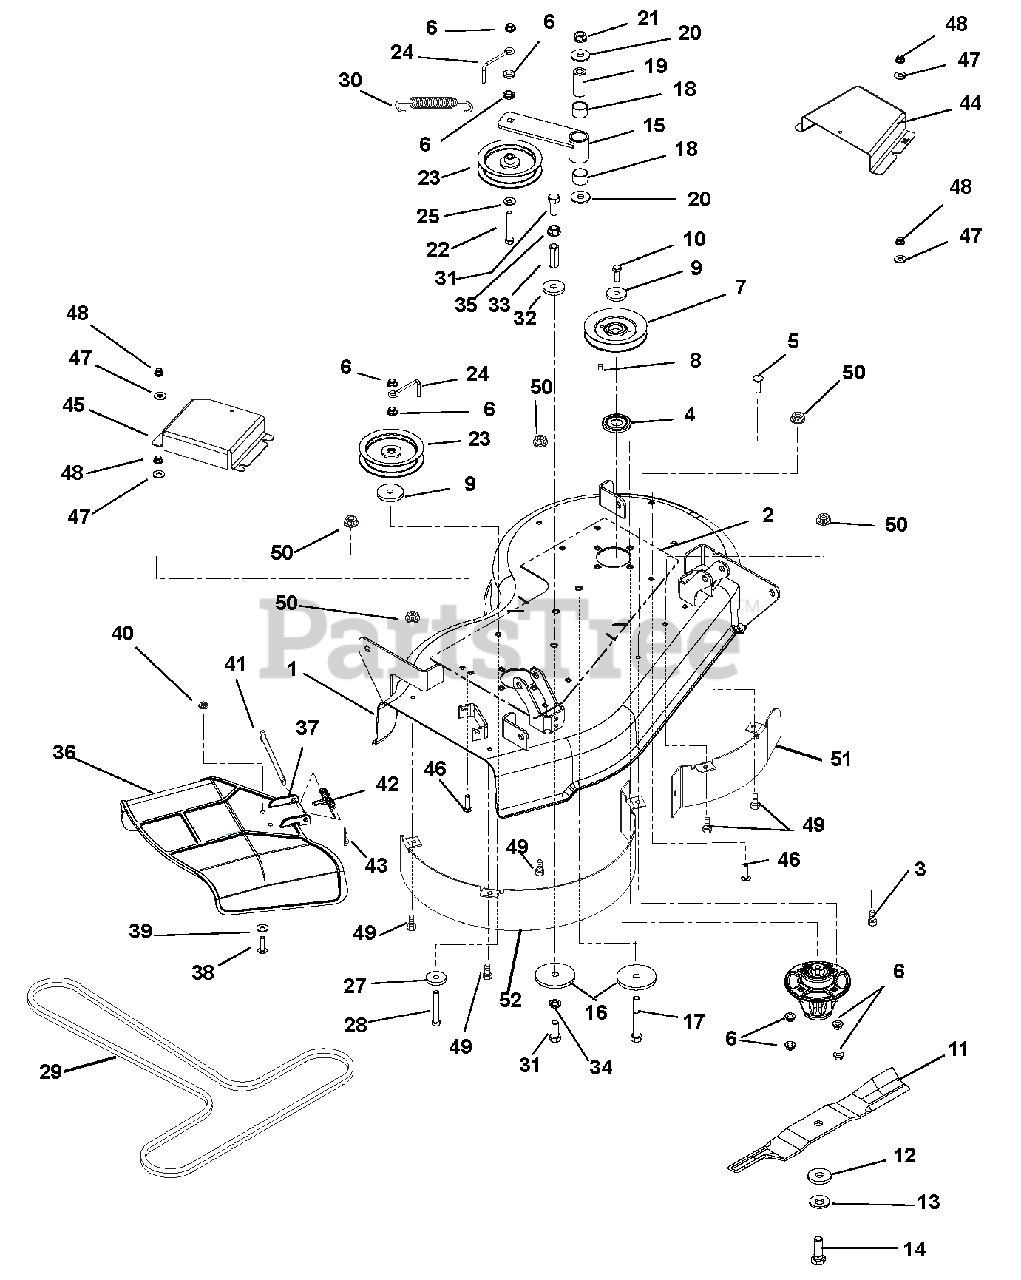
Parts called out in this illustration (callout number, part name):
1	34" DECK, STAMPED
2	DOUBLER PLATE, 34" DECK
3	SPINDLE ASSEMBLY
4	DUST CAP
5	@BLT-RDHDSQNK .38-16X1.25 G5YZ
6	@NUT-LK-NYL-FLG .38-16 YWZC
7	SHEAVE, 4.75 DIA A-SECTION
8	KEY, SQ .25 X .38 X .25
9	WSHR,FLT STL.406X1.50X.245YWZC
10	BLT-HEX .38-16X1.0 GR8 YZ EP30
11	BLADE,17.38 LG MULCH
12	WSHR-FLT .640X1.75X.250 YWZC
13	WSHR-BLVL .669X1.535X.138
14	BLT-HEX .62-18X1.75 GR8 YWZC
15	WELDMENT, IDLER ARM
16	WSHR-FL-STL .515X1.625X.250 YZ
17	@BLT-HEX .50-13X3.50 GR5 YWZC
18	BRG, 1.00 X 1.12 X .75
19	BSHG, SPCR .502X.997X2.03 PM
20	WSHR-FL-STL.511X1.441X.125 YWZ
21	@NUT-LK-TOP-FLG .50-13 YWZC
22	@BLT-HEX .38-16X2.50 GR5 YWZC
23	IDLER, FLAT .38X4.00X1.06
24	BELT FINGER
25	BSHG-FLG .406X.88X.270X.140
26	WSHR,FLT STL.406X1.50X.245YWZC
27	WSHR-FL-STL .469X2.00X.25 YWZC
28	@BLT-HEX .38-16X2.75 GR5 YWZC
29	V-BELT, HA-WRAPPED
30	EXTENSION SPRING
31	@BLT-HEX .50-13X1.25 GR5 YWZC
32	WSHR-FL-STL .515X1.625X.250 YZ
33	NUT, COUPLING 1/2-13X1.75 YWZC
34	@WSHR-LK .50X.125 REG YWZC
35	NUT-SPNLK-FLG .50-13 YWZC
36	MOLDED CHUTE, ZOOM
37	CHUTE REINFORCEMENT
38	SCR-SKH .31-18X.75 BTNHD YWZC
39	@WSHR-FL-STL.38X.875X.083 YWZC
40	@NUT-LK-TOP-FLG .31-18 YWZC
41	PIN, 5/16 X 3.88"
42	SPRING, TORSION
43	PIN-HAIR INT .08X.18X1.18 YWZC
44	BELT COVER, 34" LEFT
44	WMT, LH CE BELT COVER (34")
45	BELT COVER, 34" RIGHT
45	BELT COVER, RIGHT
46	@BLT-RHDSHSQNK.31-18X1.25 G5YZ
47	@WSHR-FL-STL.38X.875X.083 YWZC
48	@NUT-LK-NYL-FLG .31-18 YWZC
48	NUT- JAM .312-18 YWZC
49	@BLT-HEX .31-18X.75 GR5 YWZC
50	@NUT-SPNLK-FLG .312-18 YWZC
51	MULCH BAFFLE, 34" STAMPED
52	DISCHARGE BAFFLE, 34" STAMPED
